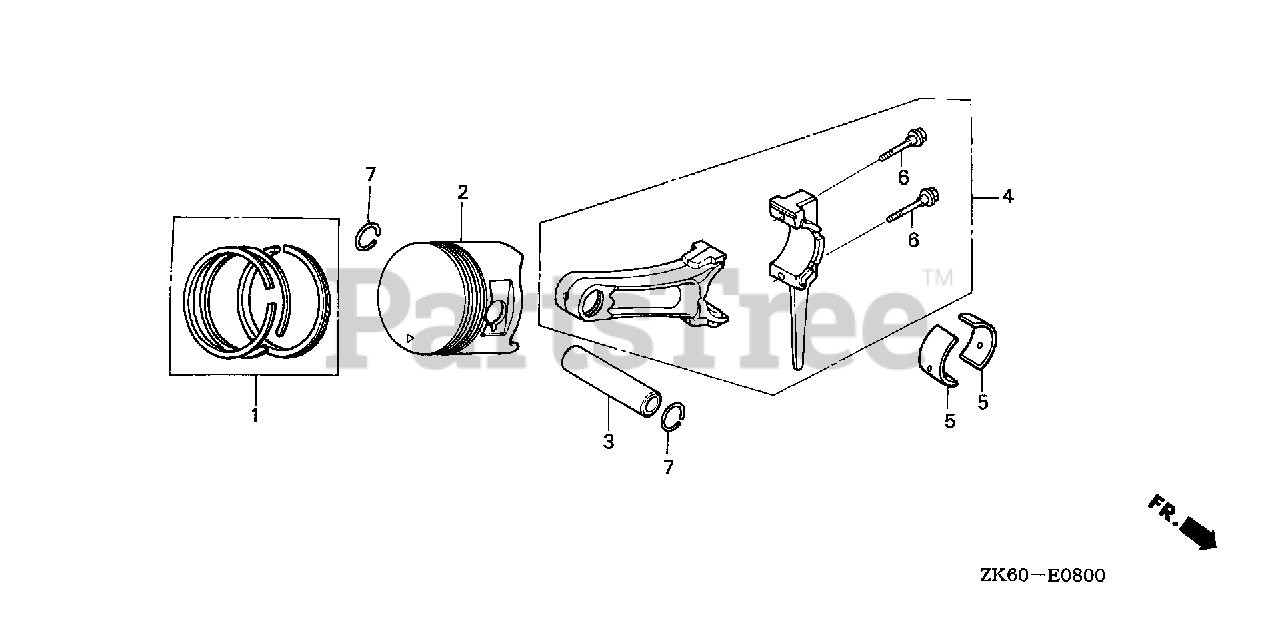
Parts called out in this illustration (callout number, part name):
1	RING SET, PISTON (STD) (NIPPON)
1	RING SET, PISTON (0.25) (NIPPON)
1	RING SET, PISTON (0.50) (NIPPON)
1	RING SET, PISTON (0.50) (TEIKOKU)
1	RING SET, PISTON (0.75) (NIPPON)
2	PISTON (STD)
2	PISTON (0.25)
2	PISTON (0.50)
2	PISTON (0.75)
3	PIN, PISTON
4	ROD ASSY., CONNECTING (STD)
4	ROD ASSY., CONNECTING (0.25 LOWER SIZE)
6	BOLT, CONNECTING ROD
7	CLIP, PISTON PIN (20MM)
